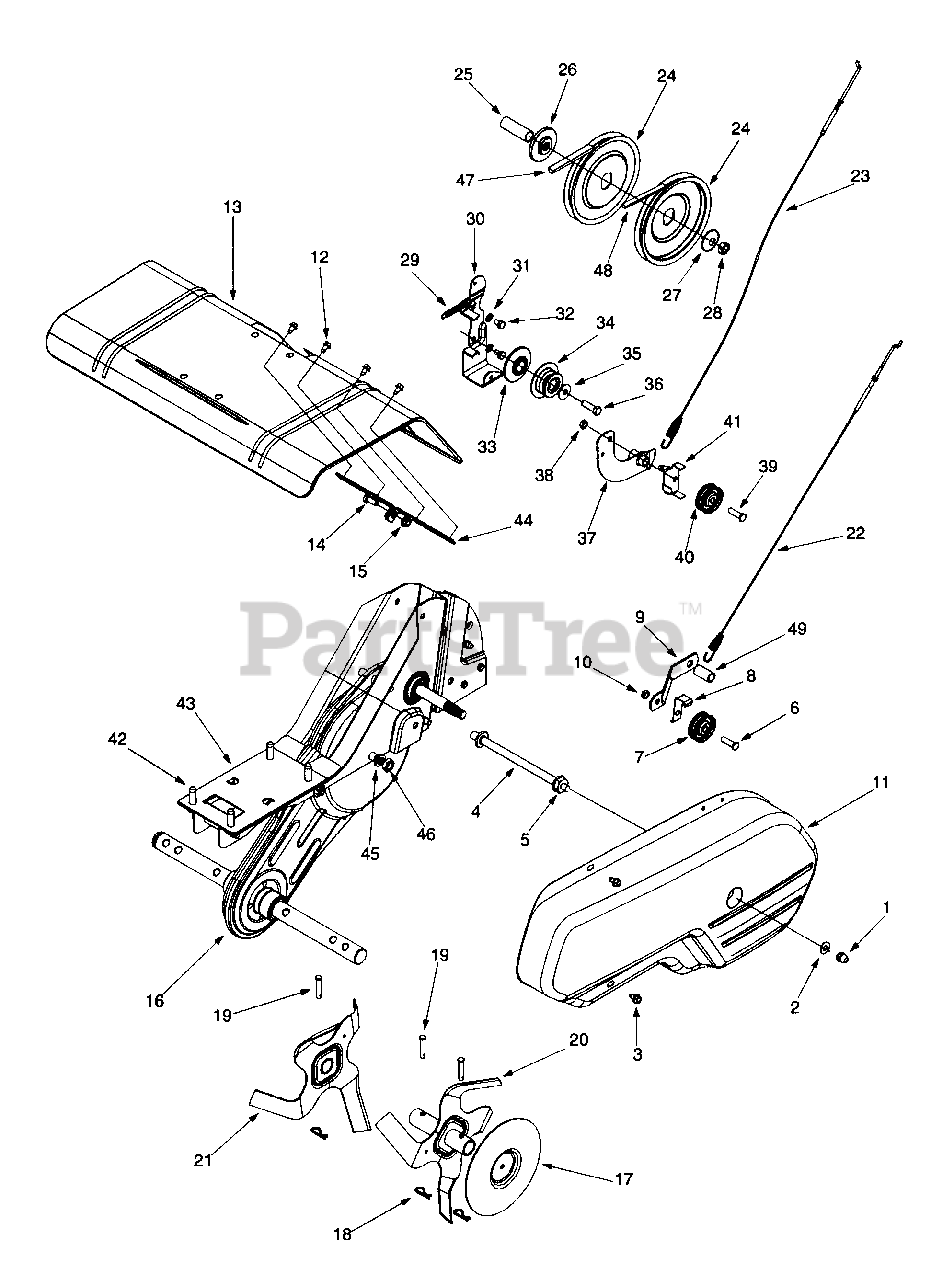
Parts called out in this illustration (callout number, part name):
1	Hex L-Stop Nut 1/4-28
2	Flat Washer .266" I.D. x .625"
3	Hex Washer Screw
4	Belt Cover Bolt
5	Hex Fl. Top L-Nut 5/16-18
6	Hex Hd. Scr. 3/8-16 x 1.25"
7	Flat Idler 2.12" O.D.
8	Idler Belt Keeper
10	Hex Cent. Jam Nut 3/8-16
12	Hex Washer Screw
14	Hex Hd. Cap Scr
15	Hex Flange Top L-Nut 5/16-18
16	Chain Case Assembly
18	Internal Cotter Pin
19	Clevis Pin
22	Forward Clutch Cable
23	Reverse Clutch Cable
24	Fl-Pulley 6" Dia.
25	Spacer .64" Dia. x 2.4"
26	Pulley Mounting Adapter
27	Bell-Wash. .525" I.D. x 1.5"
28	Hex Jam Nut 1/2-20 Thd.
29	Return Spring
31	Lock Washer 5/16
32	Hex Bolt 5/16-24 x .5"
33	Inner Engine Pulley Half
34	Outer Engine Pulley Half
35	Bell Washer .396" I.D. x 1/14"
36	Hex Bolt 3/8-24 x 1.25"
37	Reverse Arm Assembly
38	Hex Cent. Jam Nut 3/8-16
39	Hex Cap Bolt 3/8-16 x 1.25"
40	Flat Idler 2.12" O.D.
42	Hex Wash. Scr. 3/8-16 x 1.25"
45	Lock Washer 7/16" I.D.
46	Hex Nut 7/16-20 Thd.
47	V-Belt (Forward)
48	V-Belt (Reverse)
49	Shld. Bolt
